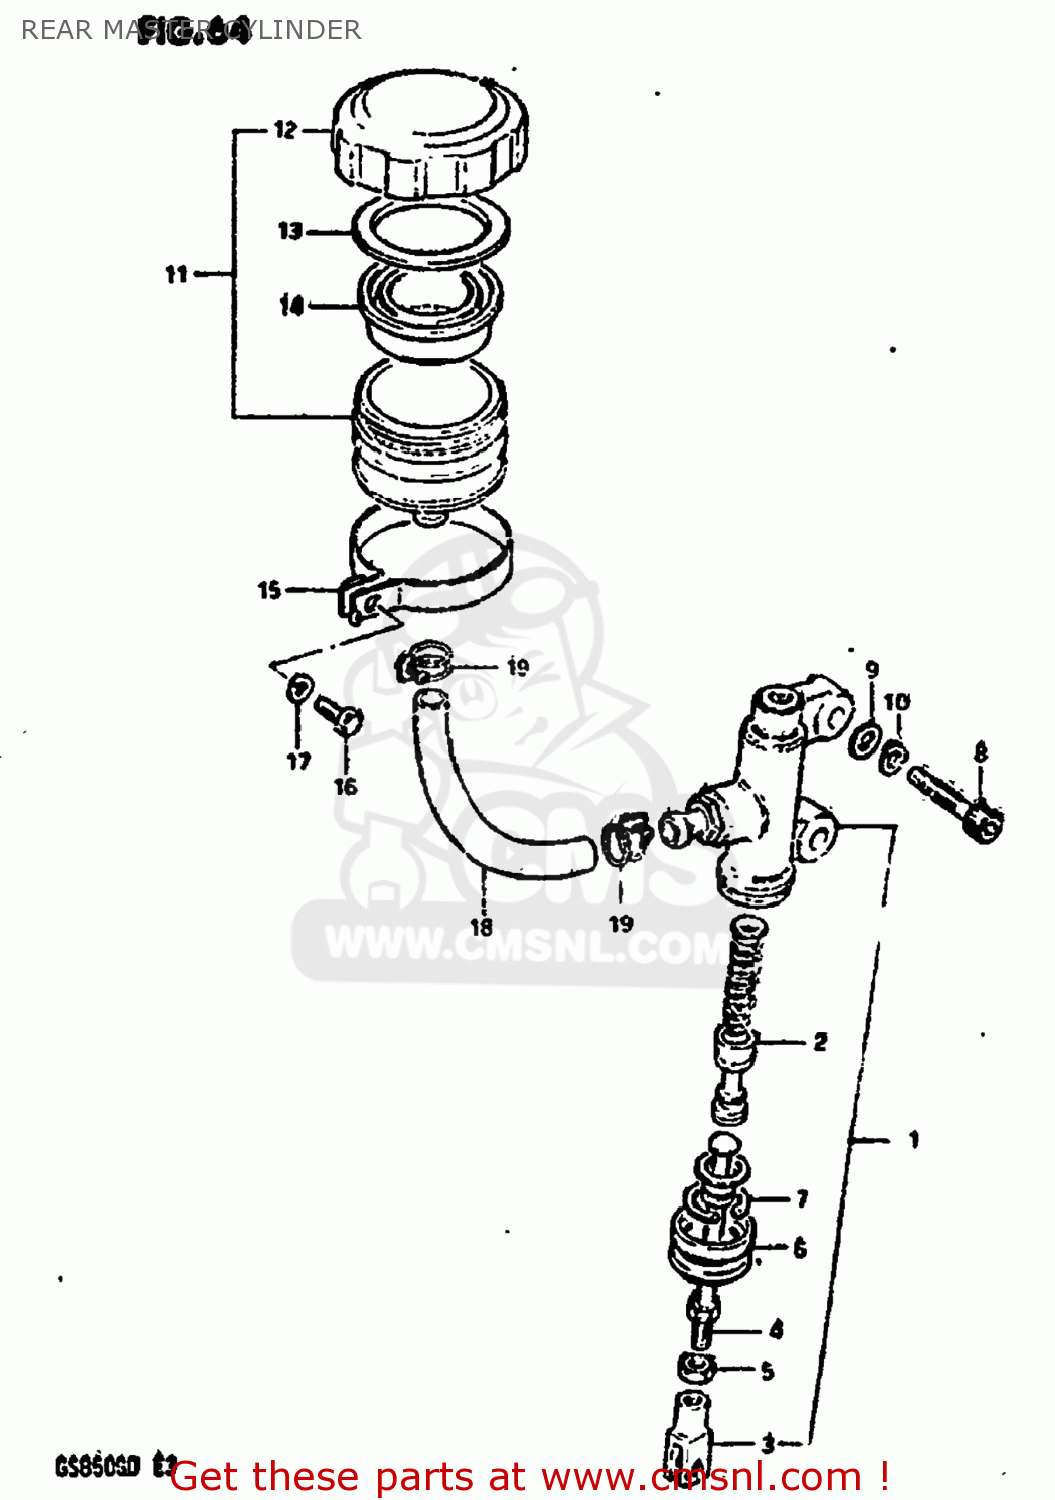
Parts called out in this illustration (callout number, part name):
1	CYLINDER ASSY,RR MASTER
2	PISTON/CUP SET
3	YOKE
4	ROD,REAR MASTER CYLINDER
5	NUT,MASTER CYLINDER
6	BOOT
7	CIRCLIP
8	BOLT
9	WASHER
10	WASHER,LOCK,8.
11	TANK ASSEMBLY,RESERVOIR
12	CAP
13	PLATE,DIAPHRAGM
14	DIAPHRAGM
15	CLAMP
16	BOLT, UPPER
17	LOCK WASHER
18	HOSE,RESERVOIR TANK
19	CLAMP
